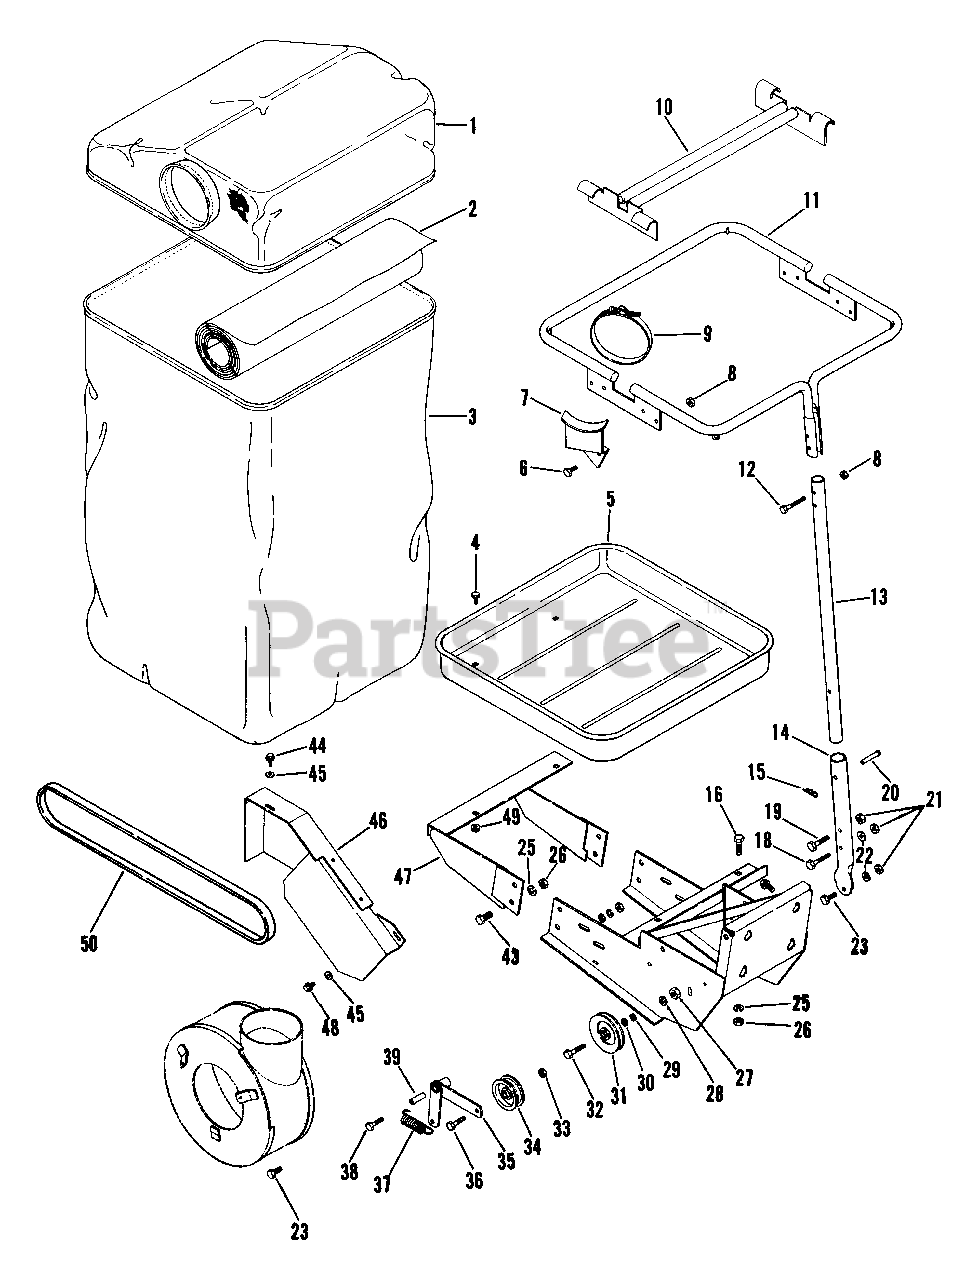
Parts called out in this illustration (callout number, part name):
2	BAGS PLASTIC
3	BAG
4	BLT-RDHDSQNK .31-18X.75 GR5 PL
5	BAG TRAY
6	BLT-HEX .31-18X.75 PL GR2
7	BRACKET-ELBOW SUPPORT
8	NUT-LK .312-18 GR A PL
9	CLAMP-HOSE WRM 2.13/8.62X.56
10	CENTER BAG SUPPORT
11	SUPPORT, BAG
12	BLT-HEX .31-18X2.25 PL GR2
13	TUBE SUPPORT
14	TUBE MOUNTING
15	PIN-HAIR INT .08X.18X1.18
16	BLT-HEX .50-13X1.50 PL GR5
17	SCREW - FLG WIZ LOCK HH PL
18	BLT-HEX .38-16X2.25 GR2
18	BLT-HEX .38-16X2.25 PL GR2
19	BLT-HEX .38-16X2.00 PL GR2
20	CLEVIS PIN
21	NUT-LK-CTR .375-16 GR A PL
22	WSHR-FL-STL .38X.875X.083 PL
23	BLT-HEX .38-16X1.00 PL GR5
25	WSHR-LK .500X.151 HVY PL
26	NUT .50-13 PL
27	NUT-HEX .375-16
28	WSHR-LK .375X.115 HVY PL
29	WSHR-FL-STL .390X.750X.125 PL
30	WSHR-FL-STL .382X.812X.062
31	IDLER-V 4.00 X .38 NWHAMSHR
32	BLT-HEX .38-16X2.00 PL GR5
33	NUT-LK-JAM-CTR .375-16 PL
34	IDLER-FLAT 2.75 X .38 DAYCO
35	IDLER ARM
36	BLT-HEX .38-16X1.50 PL GR2
37	SG-TENS .120X1.0X4.46 WLD 47
38	BLT-HEX .31-18X2.50 PL GR2
39	BSHG-SLV .334 X .50 X 1.62
40	WSHR-FL-STL .328X.875X.062 PL
41	WSHR-LK .313X.078 PL MED
42	NUT-HEX .312-18
43	BLT-HEX .50-13X1.00 PL GR2
44	SCR-TAP .250-20X.37 HWH PL TR
45	WSHR-FL-STL .380X.875X.179 PL
47	BAG SUPPORT WELDMENT
48	SCR-TAP .250-20X.75 HWH PL TR
49	NUT-FLG. .312-18 PL
50	V-BELT, HA-WRAPPED
